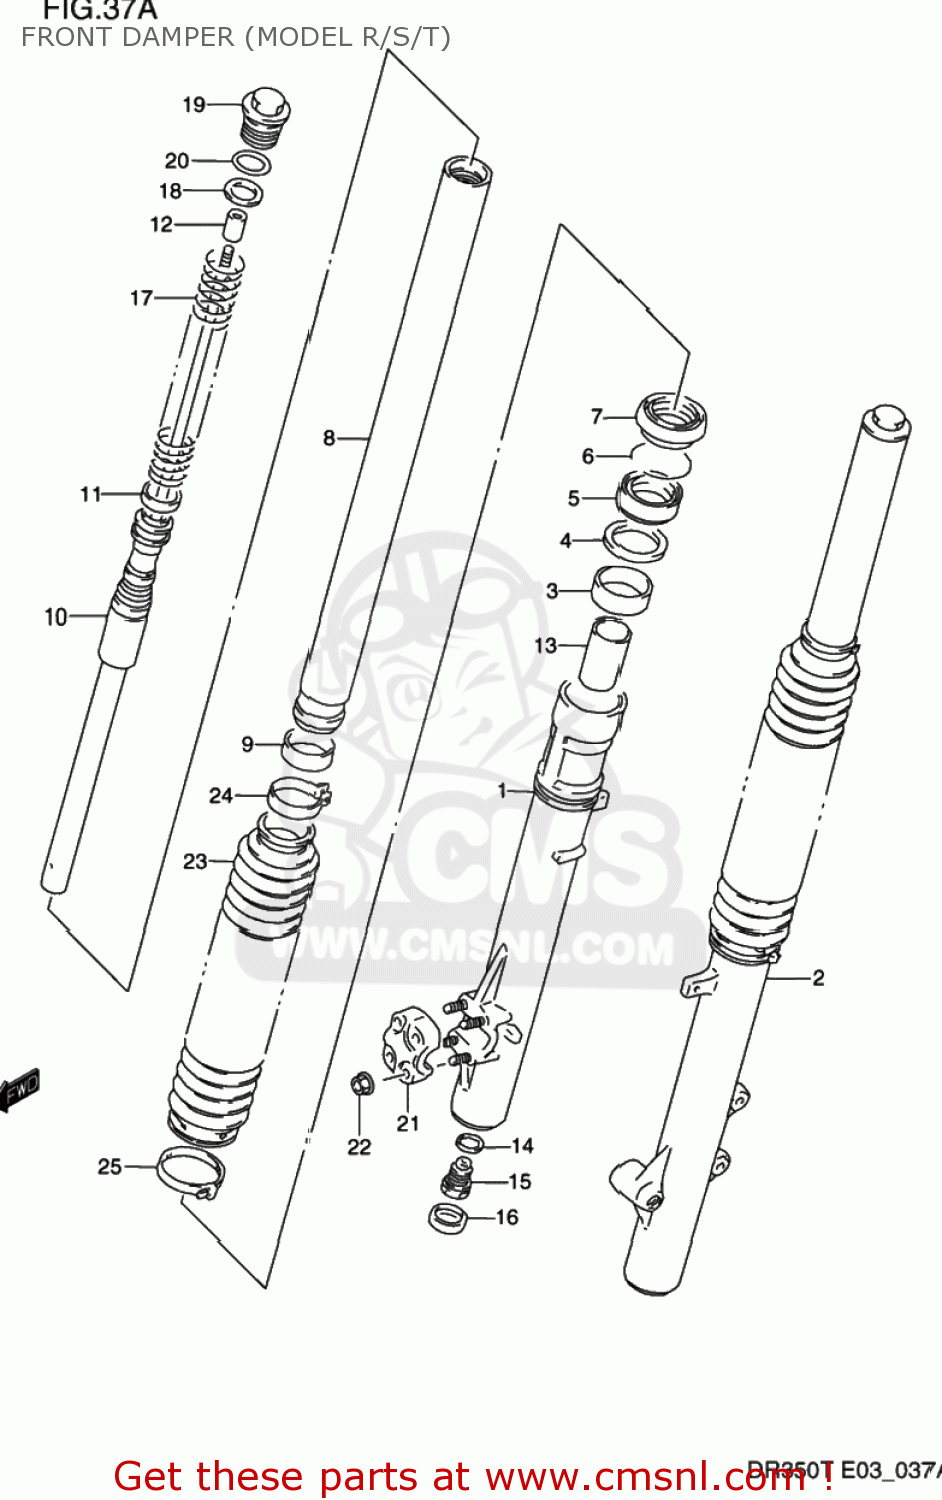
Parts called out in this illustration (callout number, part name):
1	TUBE,OUTER,RIGHT
2	TUBE,OUTER,L
3	BUSH,GUIDE
4	SPACER,SEAL
5	SEAL,OIL
6	CIRCLIP,FORK OIL SEAL
7	DUST SEAL
8	TUBE,INNER
9	BUSH,SLIDE
10	CYLINDER
11	BUSH,SLIDE
12	NUT,ROD
13	PIECE,OIL LOCK
14	GASKET (NAS)
15	CTR BOLT
16	CAP
17	SPRING,MAIN
18	SEAT,SPRING LWR
19	BOLT,FORK
20	O RING
21	HOLDER,AXLE
22	NUT,HOLDER
23	BOOT
24	BAND,BOOT UPR
25	BAND,BOOT LWR
